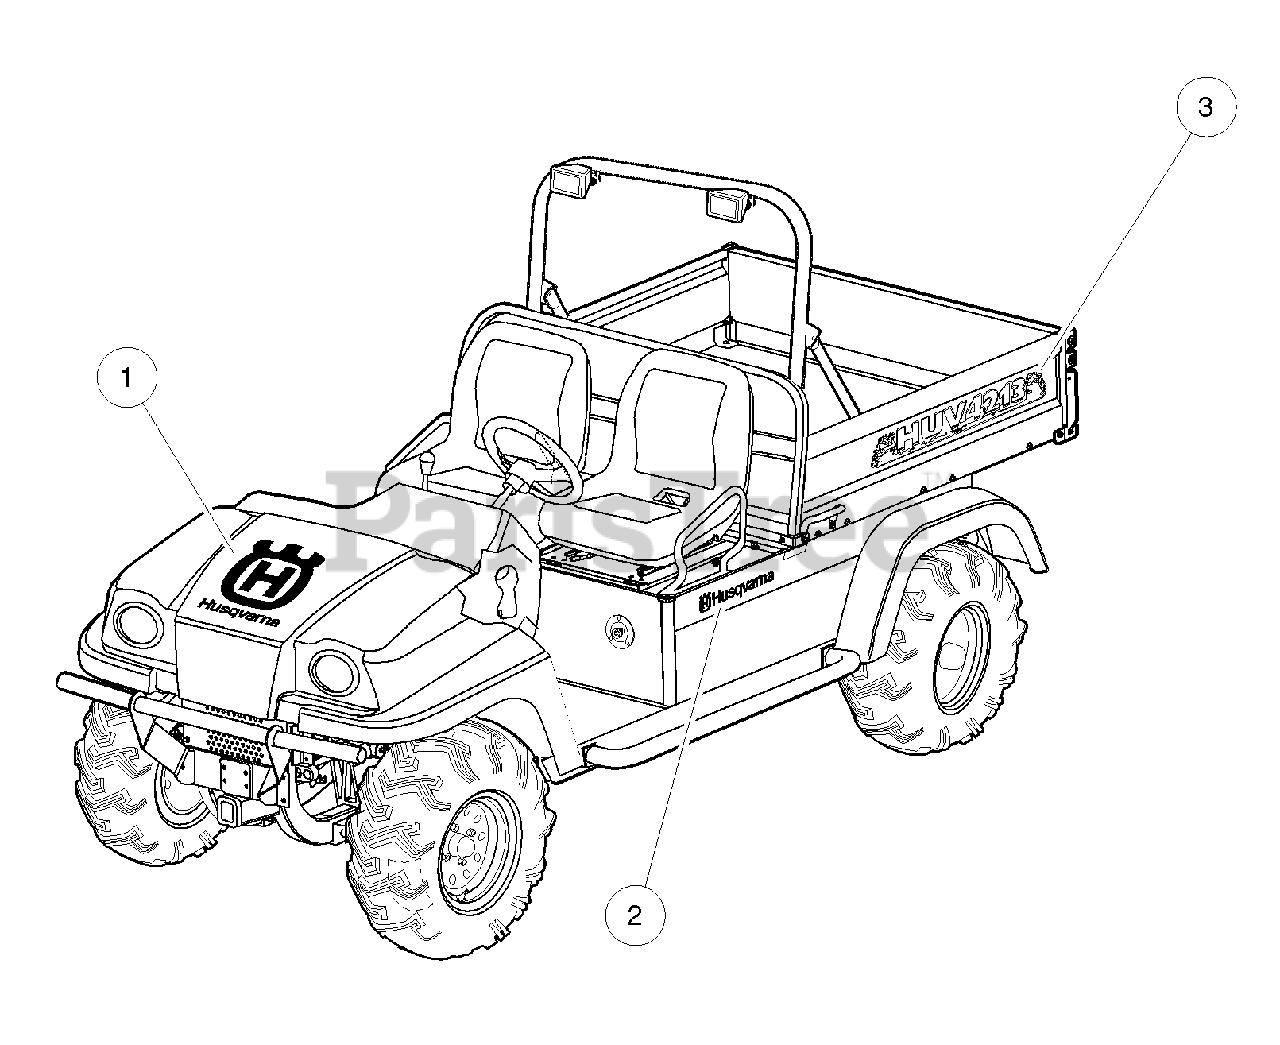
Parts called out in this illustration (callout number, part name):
1	Decal, Husqvarna Cowl
2	Decal, Husqvarna, Side Panel
3	Decal, Bed, HUV4213
